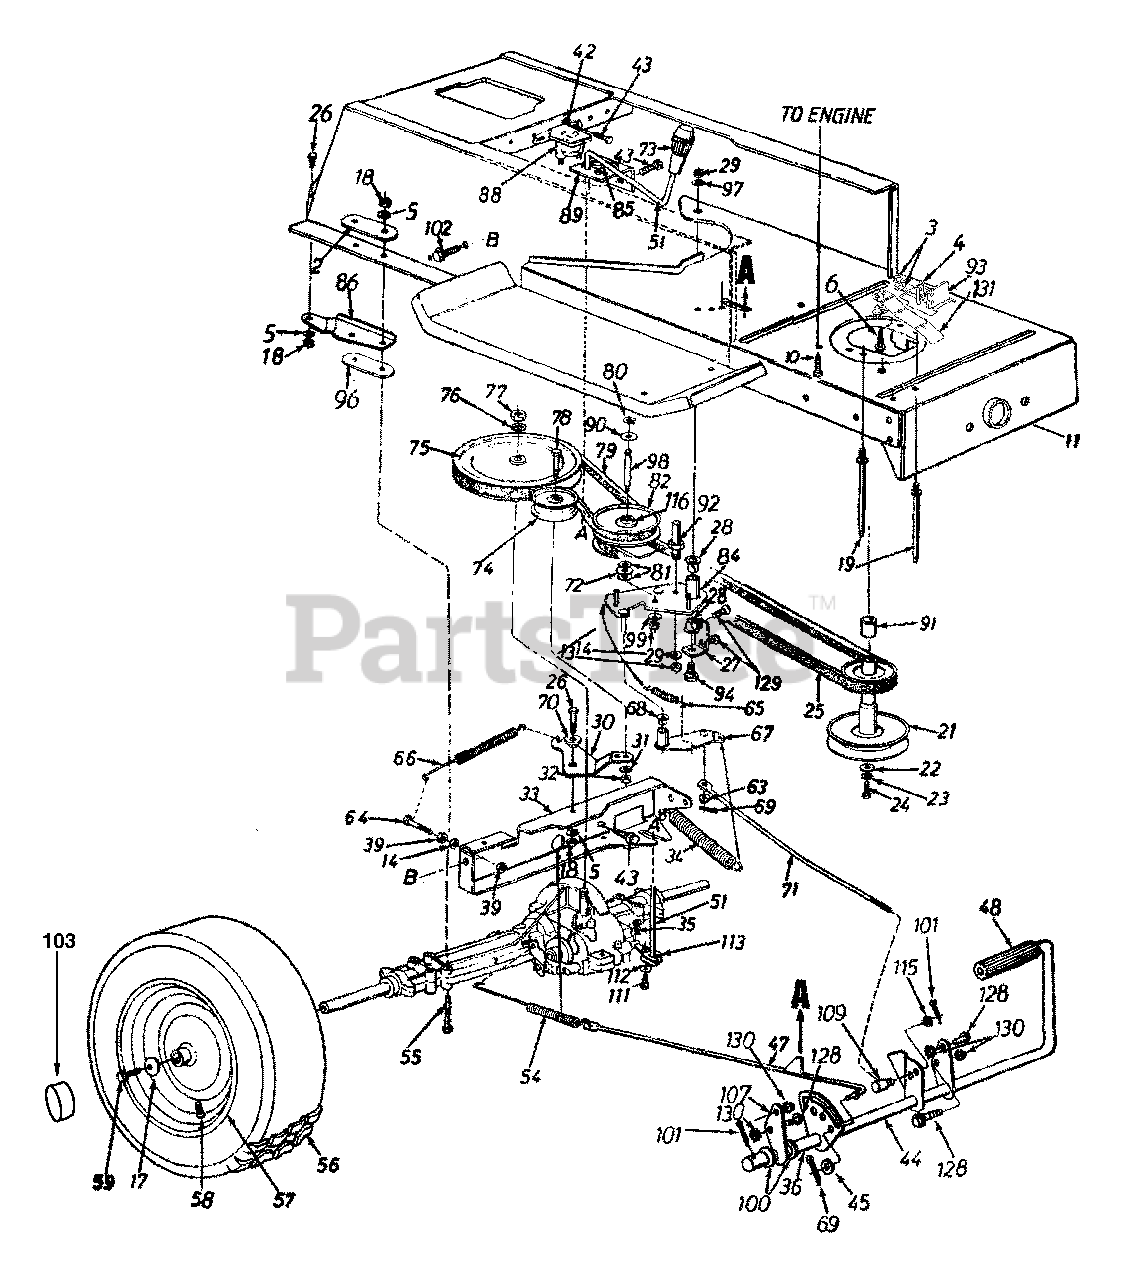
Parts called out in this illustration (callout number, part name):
3	Hex Screw #10-16
5	L-Wash. 5/16" I.D.
10	Hex TT-Tap Scr. 3/8-16 x1.5" Lg.
13	Hex Nut 1/4-20 Thd. (Gr. 5)
14	L-Wash. 1/4" I.D.
17	Bell-Wash. .345" I.D. x .88"
18	Hex Nut 5/16-18 Thd. (Gr. 5)
19	Belt Guard Stud 4.75" Lg.
21	Engine Pulley
22	Fl-Wash. 7/16" I.D. x 1.25"
23	L-Wash. 7/16" I.D.
24	Hex Bolt 7/16-20 x 1.25" Lg.
25	Variable-Speed Belt
26	Hex Bolt 5/16-18 x .75" Lg.
27	Bearing Shaft Bracket Ass'y.
28	Flanged Nyliner Brg.
29	Hex Nut 3/8-24 Thd.
31	L-Wash. 3/8" I.D.
32	Hex Nut 3/8-24 Thd.
35	Inter. Cotter Pin
36	Spacer .63" I.D.
39	Hex Nut 1/4-28 Thd.
42	Ext. L-Wash. 1/4" I.D.
43	Hx Wash. Hd. S-Tap Scr.1/4-20 x .50"
47	Brake Rod Ass'y.
48	Foot Pad
51	Shift Lever Ass'y.
54	Ext. Spring .59" O.D. x 7.08"
55	Hex Bolt 5/16-18 x 3" Lg.
58	Air Valve
59	Hex Bolt 5/16-24 x .75" Lg.
63	Fl-Wash. .34" I.D. x .68" O.D.
64	Hex Bolt 1/4-28 x 1.25" Lg.
65	Ext. Spring
66	Ext. Spring .62" O.D. x 6.12"
68	Flanged Bearing
69	Cotter Pin 3/32" Dia.
70	Shoulder Spacer .27" Lg.
71	Speed Control Link
72	Truss Bearing .56 Dia. x 1.25"
73	Shift Knob
74	Fl-Idler Pulley 3.12" Dia.
76	Bell-Wash. .56" I.D. x 1.125"
77	Hex Jam Nut 5/16-18 Thd.
78	Hex Bolt 3/8-24 x 1.75" Lg.
79	Variable Speed Belt
80	Snap Ring .56" Dia.
82	Variable Speed Pulley Ass'y. 5" O.D.
90	Teflon Washer .565" I.D.
91	Spacer 1" I.D. x 1.25" Lg.
92	Belt Keeper 3" Lg.
93	Safety Switch (Clutch)
94	Shld. Bolt 3/8-24 x 3.12" Lg.
97	Bell-Wash. .38" I.D. x .88"
98	Shaft .56" Dia. x 3.875" Lg.
99	Bell-Wash. .39" I.D. x 1.12"
100	Fl-Wash. .64" I.D. x .94"
101	Cotter Pin 1/8" Dia. x 1.25"
102	Hex Wash. Hd. Scr. 5/16-18 x .62"
103	Hub Cap LT-1500
111	Hex Bolt 1/4-28 x .50" Lg.
112	Bell-Wash. .265" I.D. x .75"
113	Shift Lever Link Ass'y.
115	Fl-Wash. .385" I.D. x .62"
116	Needle Brgs.
128	Hex Wash. TT-Tap Scr. 5/16-18 x .75"
129	Hex Wash. AB-Tap Scr. 5/16-18 x .75"
130	Hex Sems Nut 5/16-18 Thd.
131	Spring Switch
